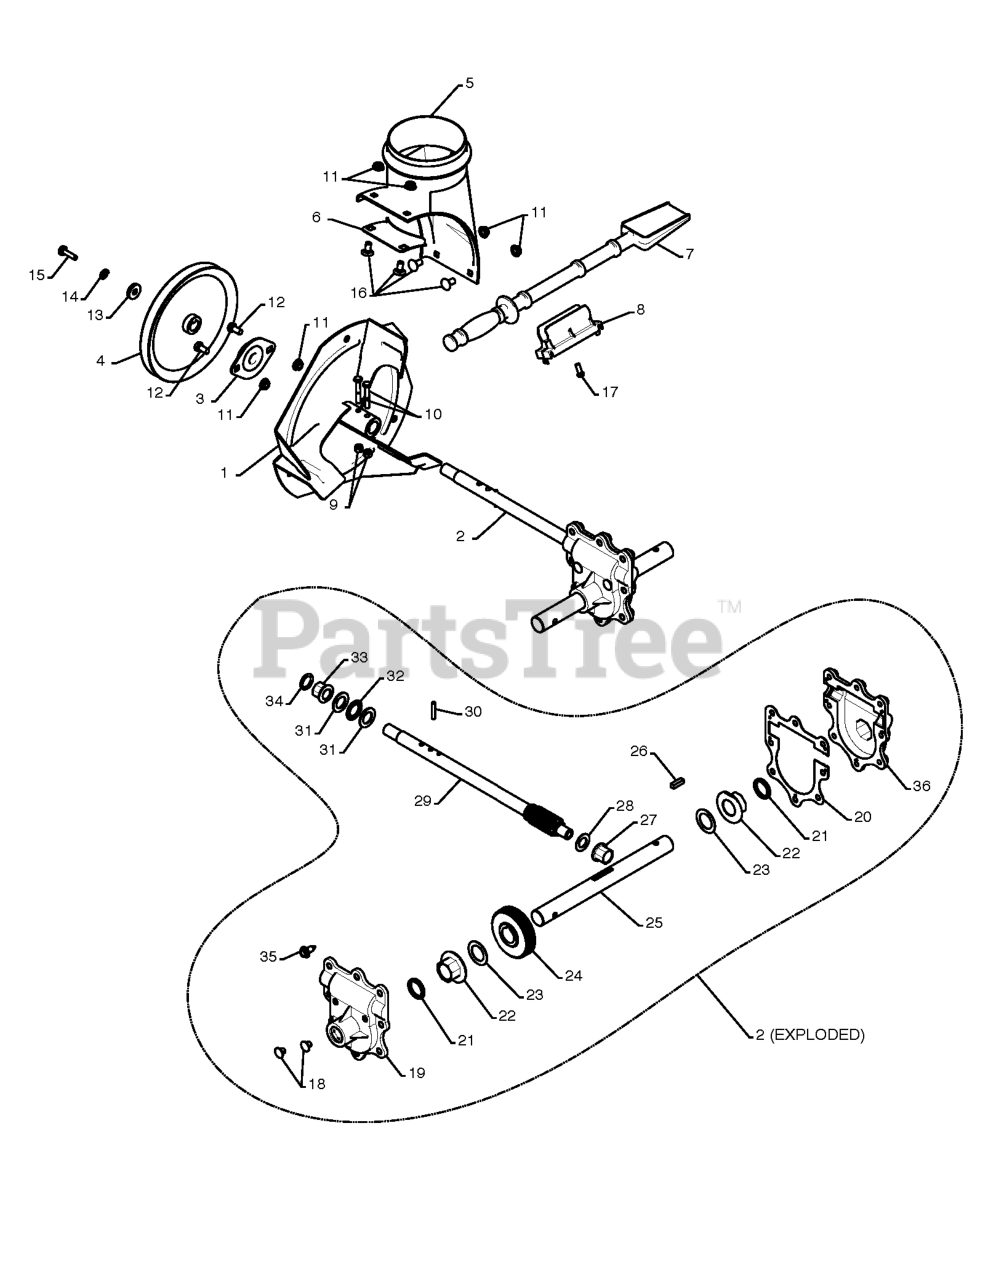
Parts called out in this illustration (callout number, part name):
1	IMPELLER ASSY
2	GEARBOX.ASSEMBLY.AUGER
3	BEARING FLANGE
4	PULLEY, IMPELLER
5	BASE DISCHARGE CHUTE
6	BRACKET, CORNER DISCHARGE
7	CLEAN OUT TOOL
8	CLIP.CLEANOUT.TOOL
9	LOCKNUT.NYLOC.1/4-20
10	SCREW.HEX.HD1/4-20X
11	NUT.FLANGE.5/16
12	BOLT, HEX HEAD 5/16-18
13	WASHER, FLAT
14	WASHER.LOCK.HVY.HLCL.SPR.5/16
15	CAPSCREW.HX.HD.5/16-18X1.00.NY
16	BOLT.CARRIAGE.5/16-18X
17	SCREW.HWH.13-16-5.8.BZP
18	CASE PLUG
19	GEARBOX HOUSING-RH
20	GEARBOX GASKET
21	OIL SEAL
22	FLANGE BUSHING-1"
23	WASHER TRUST 1"
24	WORM GEAR
25	AUGER SHAFT
26	KEY, SQUARE 1/4 X .875
27	FLANGE BUSHING-5/8
28	WASHER, THRUST 5/8
29	SHAFT, IMPELLER
30	PIN, ROLL 3/16 X 1-1/8
31	WASHER, THRUST 3/4
32	BEARING TRUST 3/4 NTA-1220
33	BUSHING, FLANGE 3/4
35	HEX SCREW-5/16 X 3/4
36	HOUSING.GEARBOX.LH(SERVICE)
